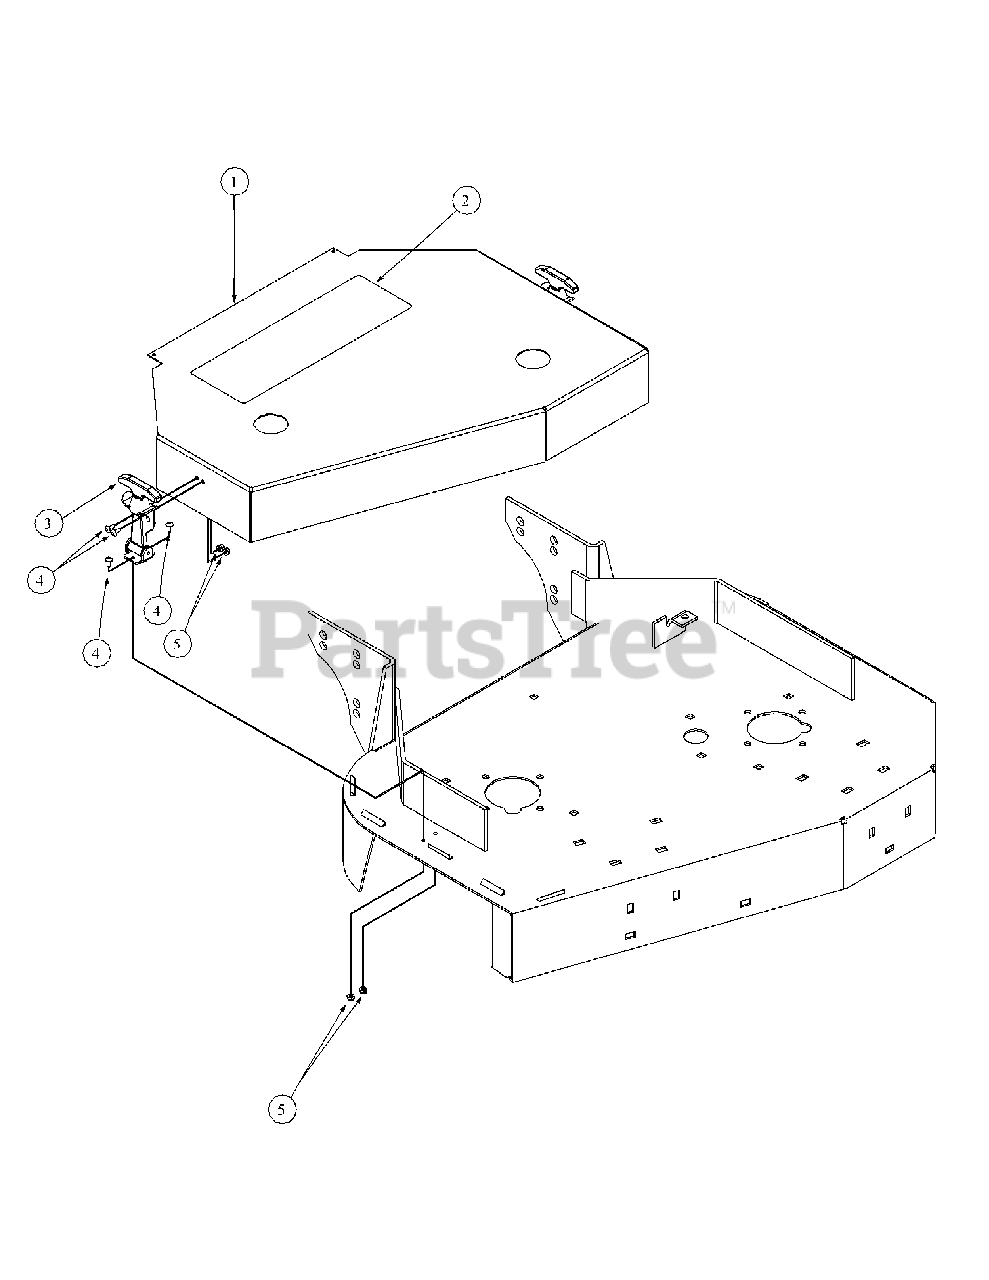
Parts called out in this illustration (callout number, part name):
1	Deck Cover, 32"
2	Decal, 32"
3	Rubber Hood Latch
4	Machine Screw, 10-24 x 1/2
5	Lock Nut, Nylon Insert, 10-24
